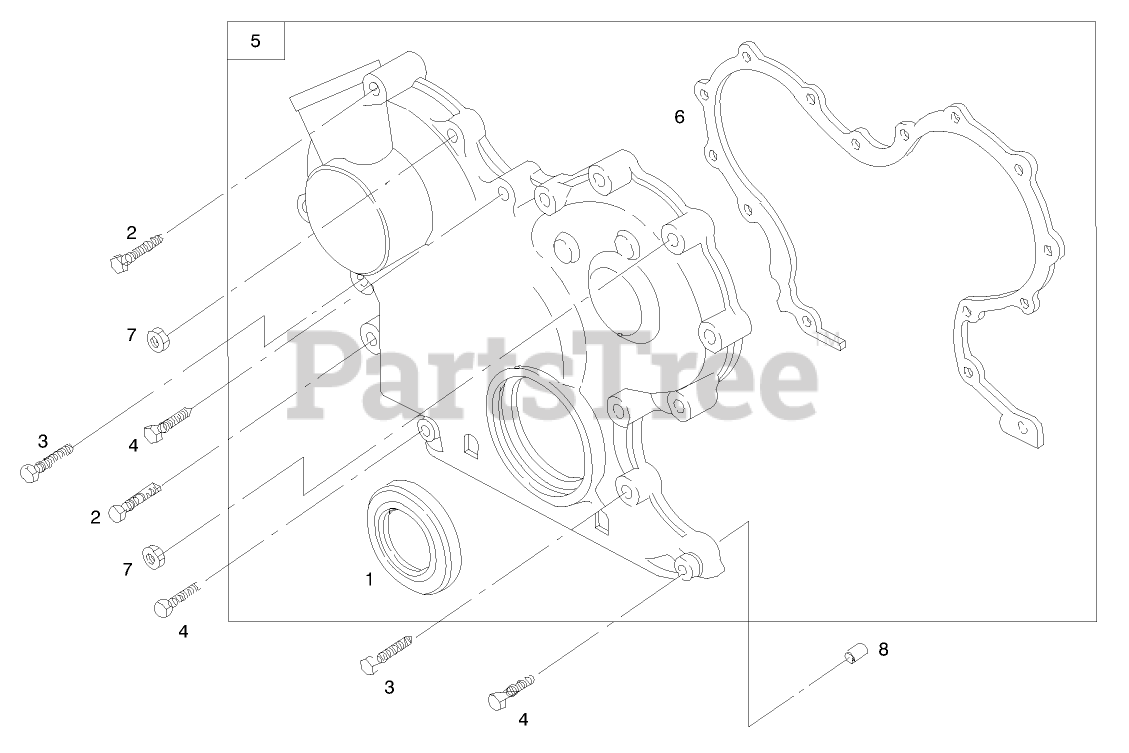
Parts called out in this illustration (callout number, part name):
2	SCREW-HEX
3	SCREW-HEX
4	SCREW-HEX
6	GASKET-COVER, GEAR
7	NUT-HEX, METRIC
8	PIN-LOCATING
